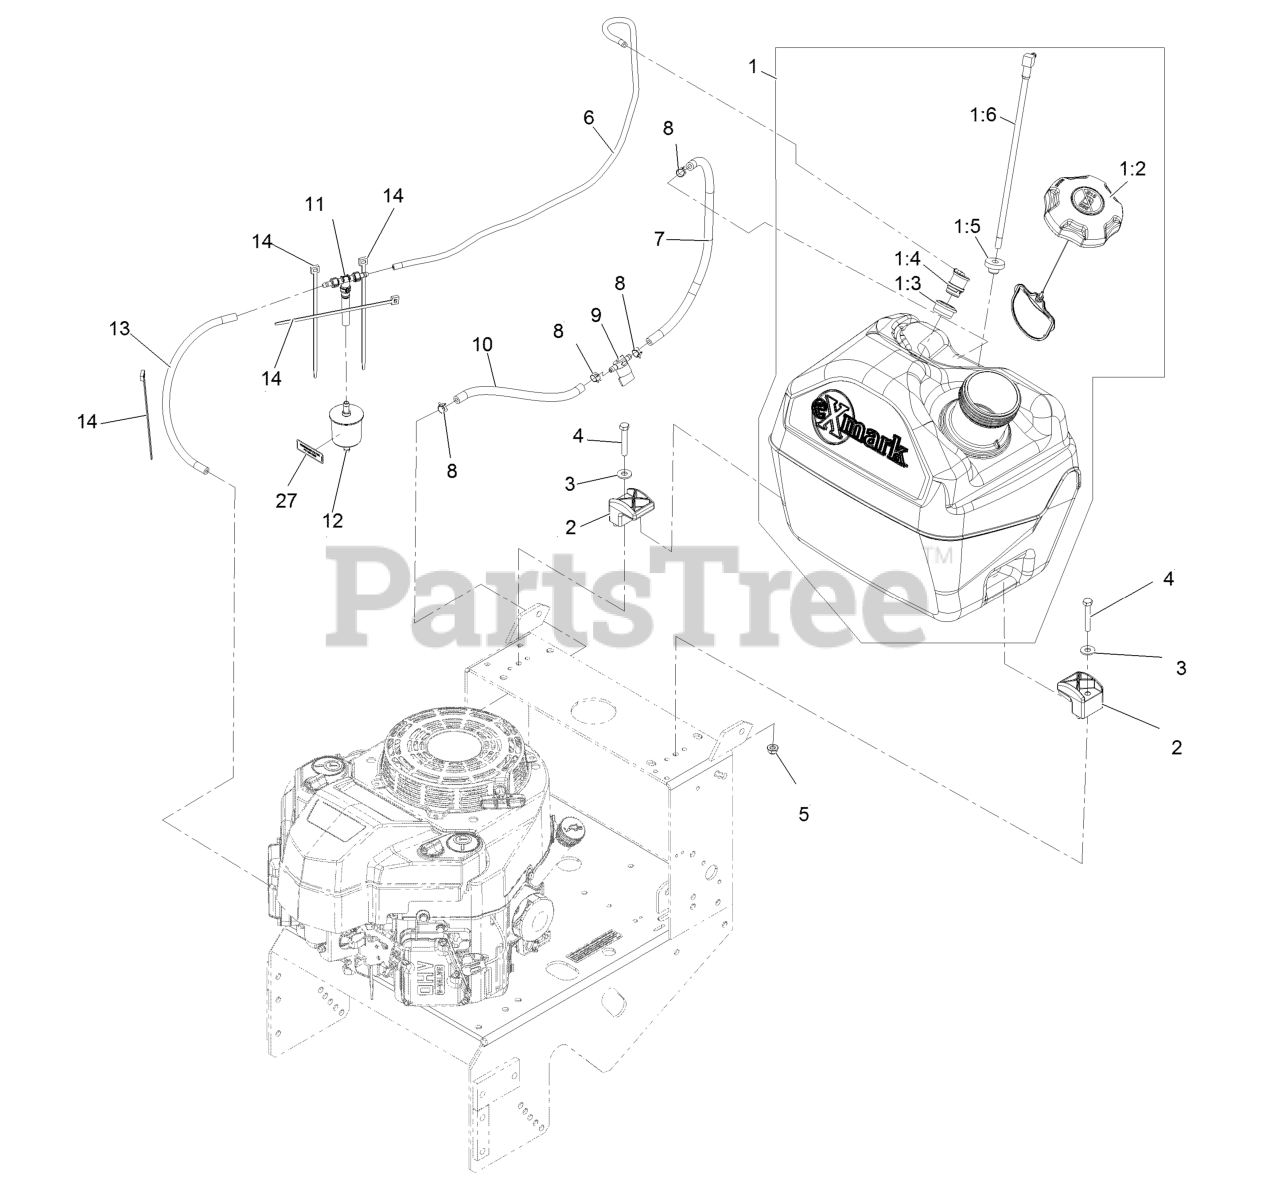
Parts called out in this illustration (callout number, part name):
1	ASM, Fuel Tank 5 Gal
1:2	Cap-Fuel, Ratcheting
1:3	Grommet
1:4	Valve-Vent, Fuel
1:5	Bushing
1:6	Fitting-Fuel (W/Line And Screen)
3	Washer-5/16 Std
4	Screw-HH 5/16-18 X 2
5	Nut-Nyloc 5/16-18 Flg
6	Hose-Emissions
7	Hose-Fuel
8	Clamp-Hose
9	Valve-Fuel
10	Hose-Fuel Line 8 1/2"
11	Tee And Check
12	Filter-Fuel
13	Hose-Fuel
14	Tie-Cable 7 15/16 (Large)
27	Decal-Filter, Emissions
28	Pn 41019-1055 Filter W/6In Fuel Line
